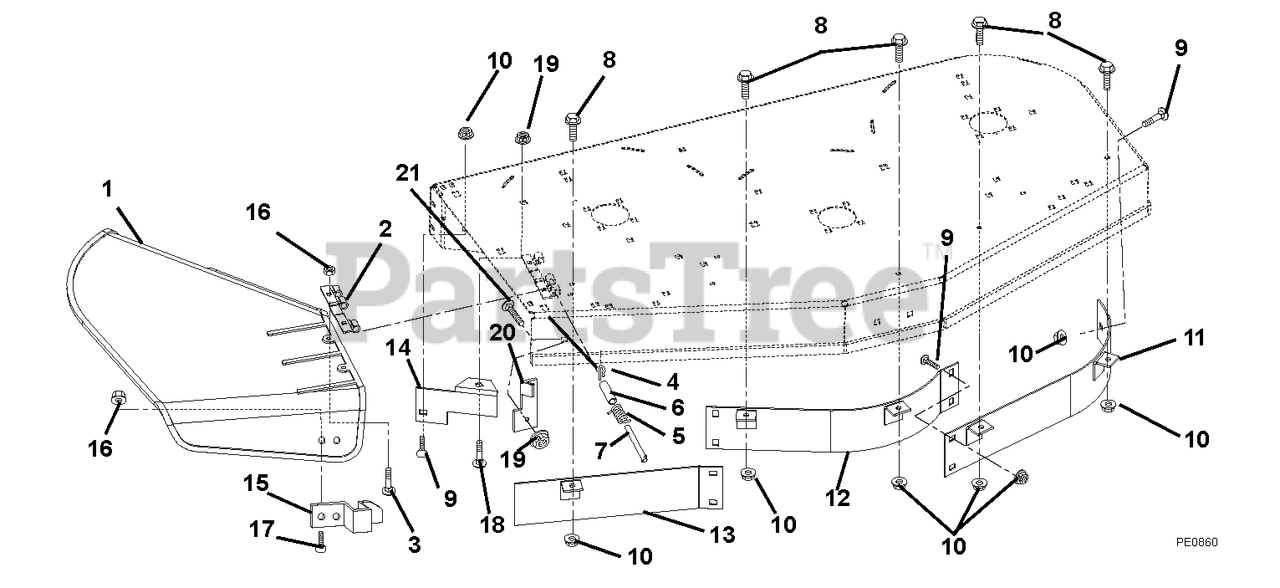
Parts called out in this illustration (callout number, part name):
1	DEFLECTOR, CHUTE
2	HINGE PLATE
3	@BLT-RDHDSQNK .25-20X.75 G5YZ
4	PIN-HAIR INT .08X.18X1.18 YWZC
5	SG-TORS .095X.50X 1.0
6	BSHG-SLV .334 X .502 X 1.437
7	PIN, 5/16 X 5.80"
8	BLT-SERHFWH .312-18X.75 YWZC
9	@BLT-RHDSSQNK .31-18X.75 G5YZ
10	@NUT-LK-NYL-FLG .31-18 YWZC
11	BAFFLE-LEFT FRONT-40"
12	BAFFLE-CENTER FRONT-40"
13	BAFFLE-RIGHT FRONT-40"
14	DEFLECTOR, 40" (400)
15	FLAT SPRING
16	@NUT-LK-TOP-FLG .25-20 YWZC
17	@BLT-RDHDSQNK .25-20X.50 G5YZ
18	@BLT-RDHDSQNK .38-16X1.00 G5YZ
19	@NUT-LK-NYL-FLG .38-16 YWZC
20	BRACKET, CHUTE LOCK
21	@BLT-RDHDSQNK .38-16X1.50 G5YZ
